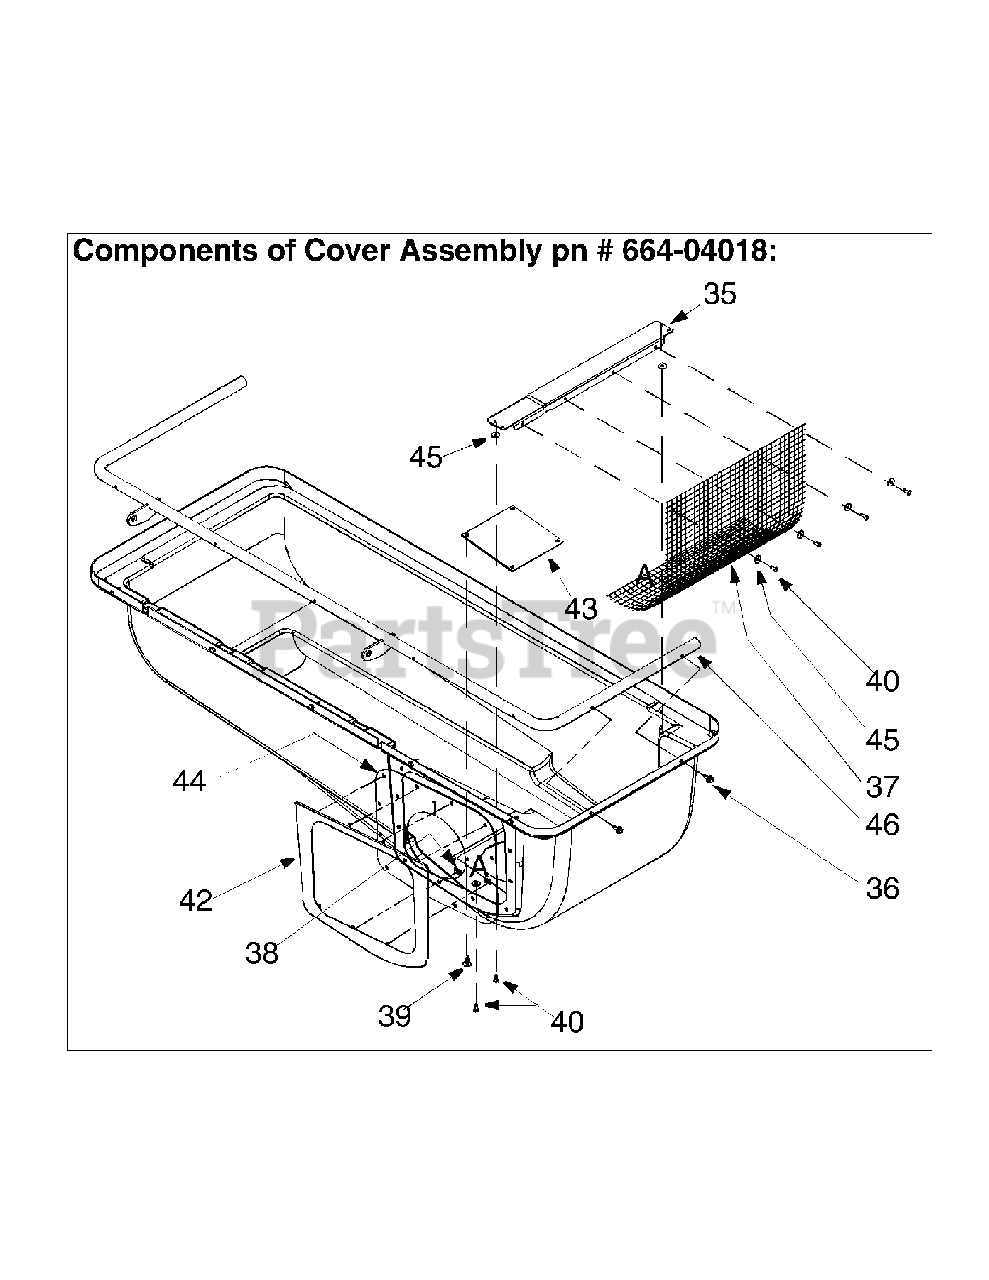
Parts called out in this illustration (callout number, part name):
39	Ratchet Clip
40	Pop Rivet
42	Retainer Seal
43	Plastic Plate
44	Grass Bag Seal
45	Flat Washer
46	Hinge Bracket
